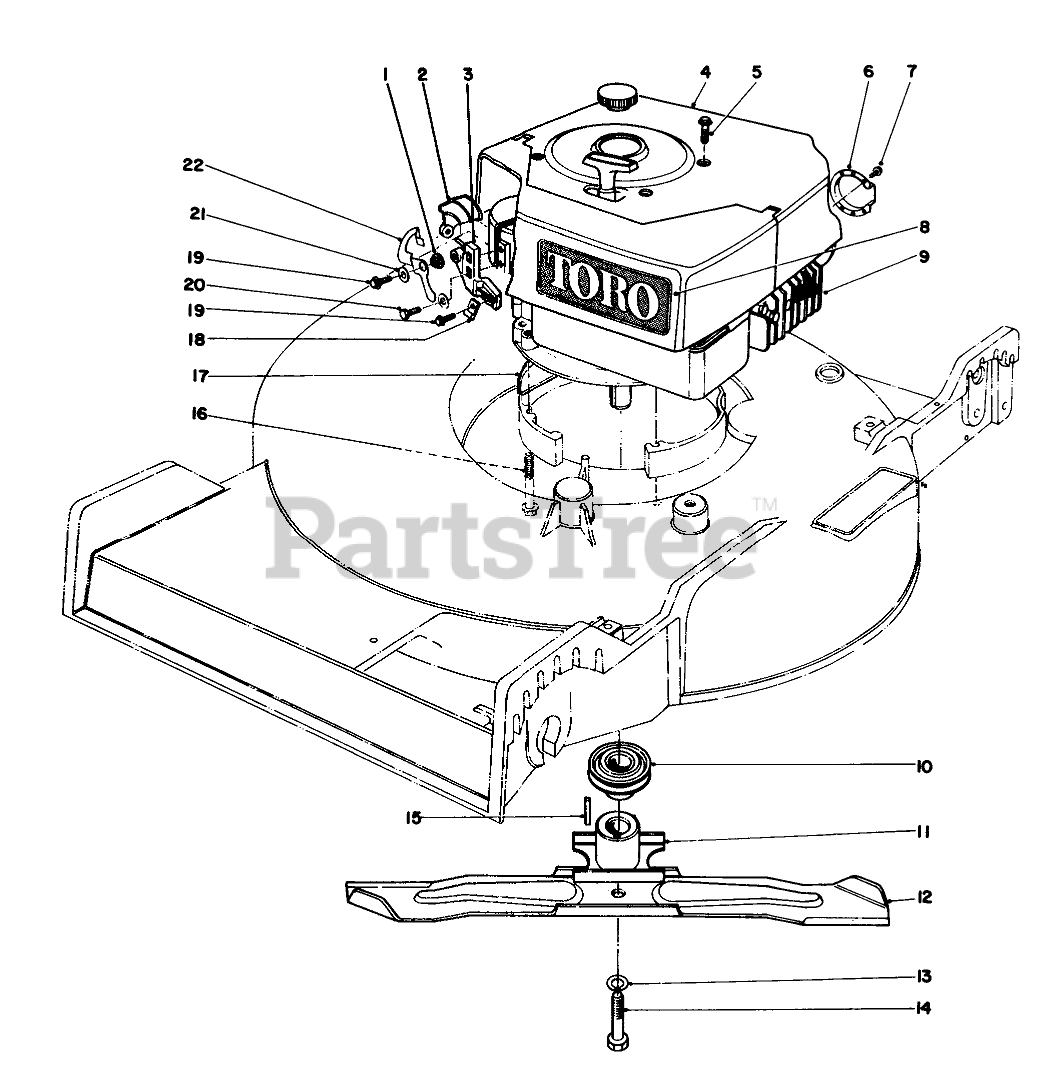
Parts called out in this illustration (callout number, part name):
1	BUSHING
2	INTERLOCK LEVER
3	CABLE & PIVOT BLOCK
4	SHROUD
5	TAPPING SCREW
6	Deflector
7	SCREW W/ENGINE
8	Decal Tow
9	Engine
10	Pulley
11	BLADE RETAINER WA(BLACK)
12	Blade
13	WASHER-LOCK
14	BLADE SCREW
15	KEY-SQUARE
16	3/8-16 X 2 CAPSCREW
17	HOUSING CAP
18	CLAMP
19	SCREW-HWHTF
20	SCREW-SHWH
21	WASHER-FLAT
22	CAM INTERLOCK
